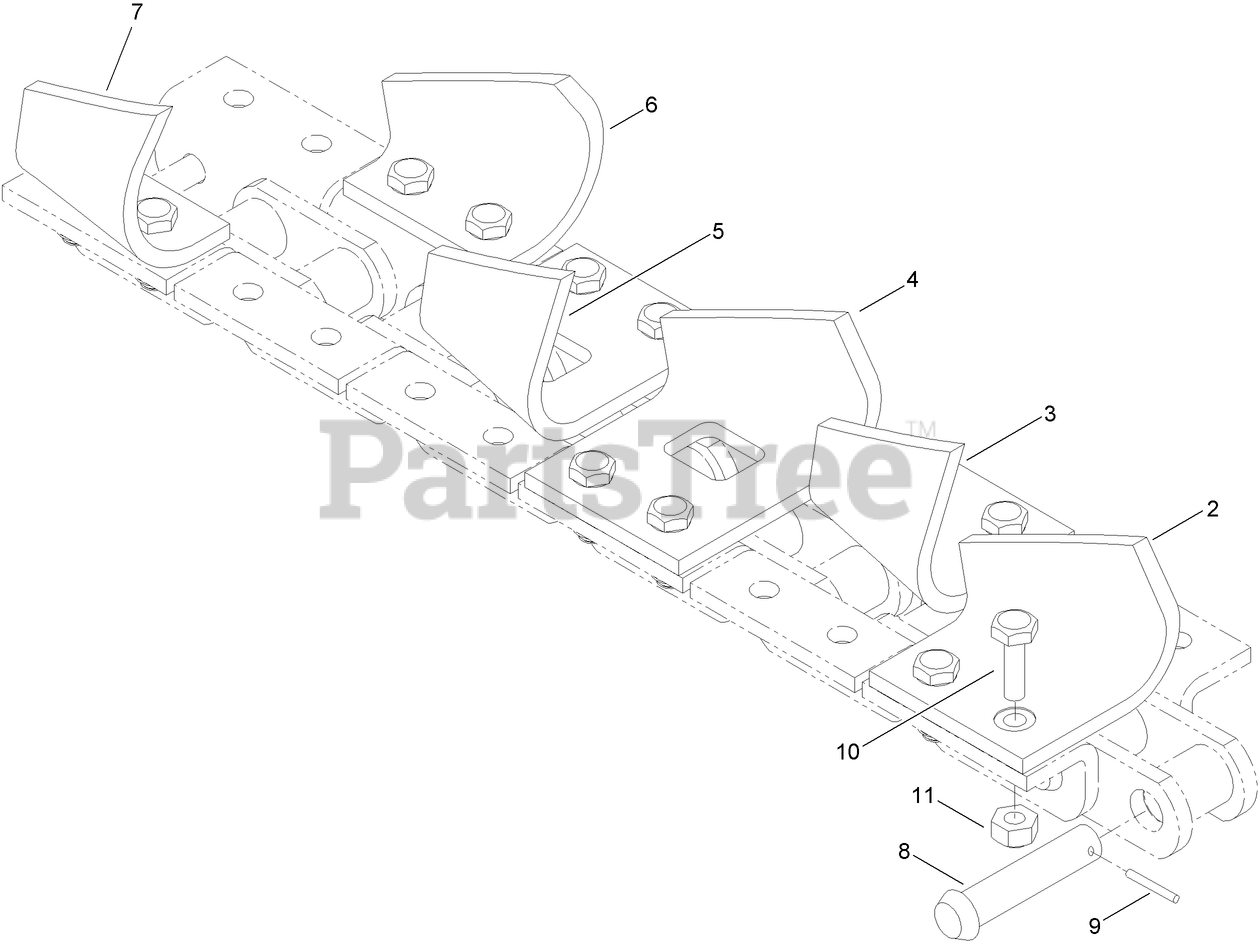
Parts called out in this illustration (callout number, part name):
2	TOOTH-CUP (1"-8" L)
3	TOOTH-CUP (1"-8" R)
4	TOOTH-CUP (3" L)
5	TOOTH-CUP (3" R)
6	TOOTH-CUP (6" L)
7	TOOTH-CUP (6" R)
8	PIN-MASTER
9	PIN-KEEPER, MASTER
11	NUT-LOCK
